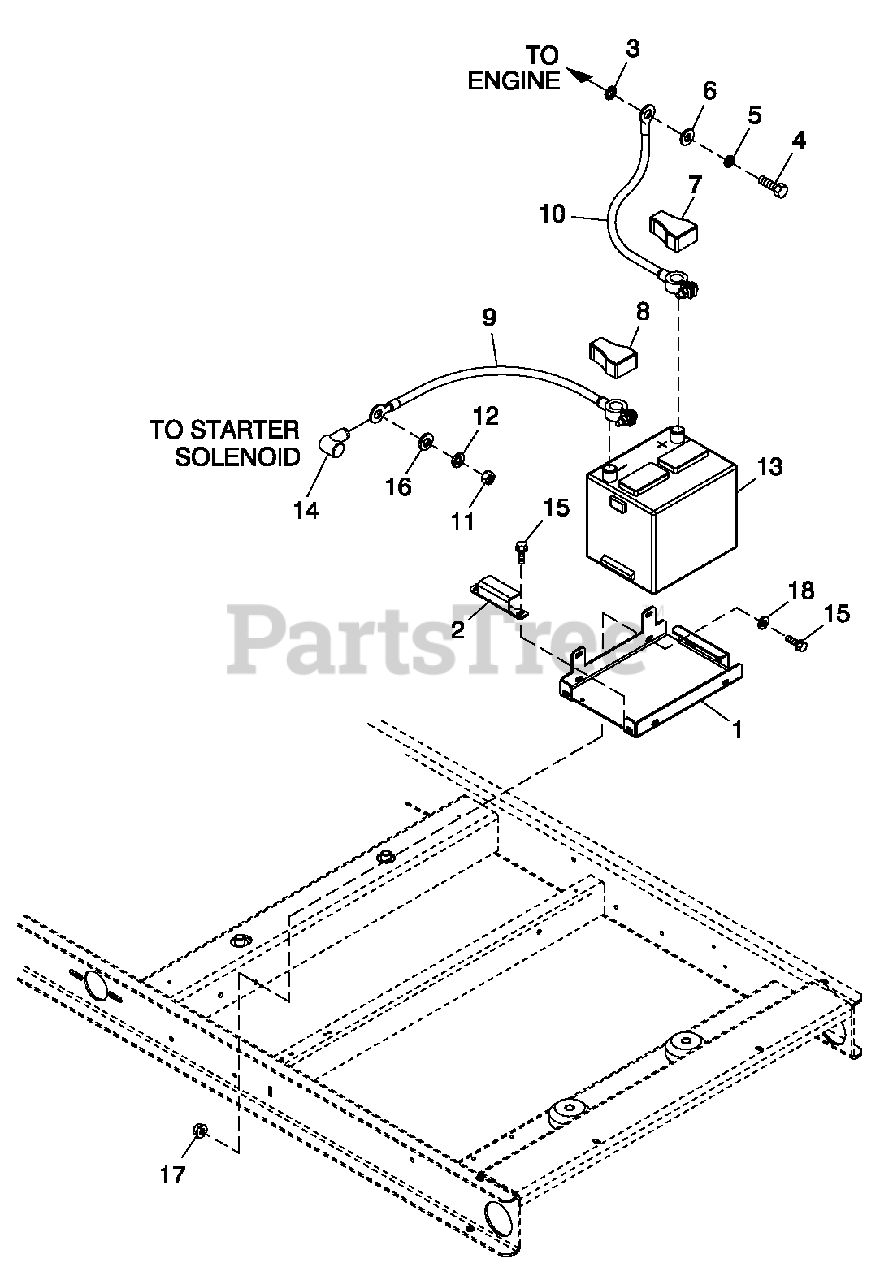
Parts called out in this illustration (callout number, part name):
1	BATTERY TRAY, C1&C2
2	STRAP BATTERY RETAINMENT
3	WASHER SHAKEPROOF EXT 7/16 STL
4	SCREW HHC M10-1.25 X 25 G8.8
5	WASHER LOCK M10
6	WASHER FLAT 3/8-M10 ZINC
7	BATTERY POST COVER RED +
8	BATTERY POST COVER B LACK -
9	CAB LE BATTERY B LACK #1 X 18.00
10	CAB LEBATT RED #1X18.00
11	NUTHEXM8-1.25 G8 YE L CHR
12	WASHER LOCK M8-5/16
13	BATTERY 12VDC 75-AH 26
14	BOOT CONTACTOR CAB LES
15	SCREW HHC M6-1.0X 20 C8.8
16	WASHER FLAT 5/16-M8 ZINC
17	NUT FLANGE M6-1.0 NYLOK
18	WASHER FLAT M6
